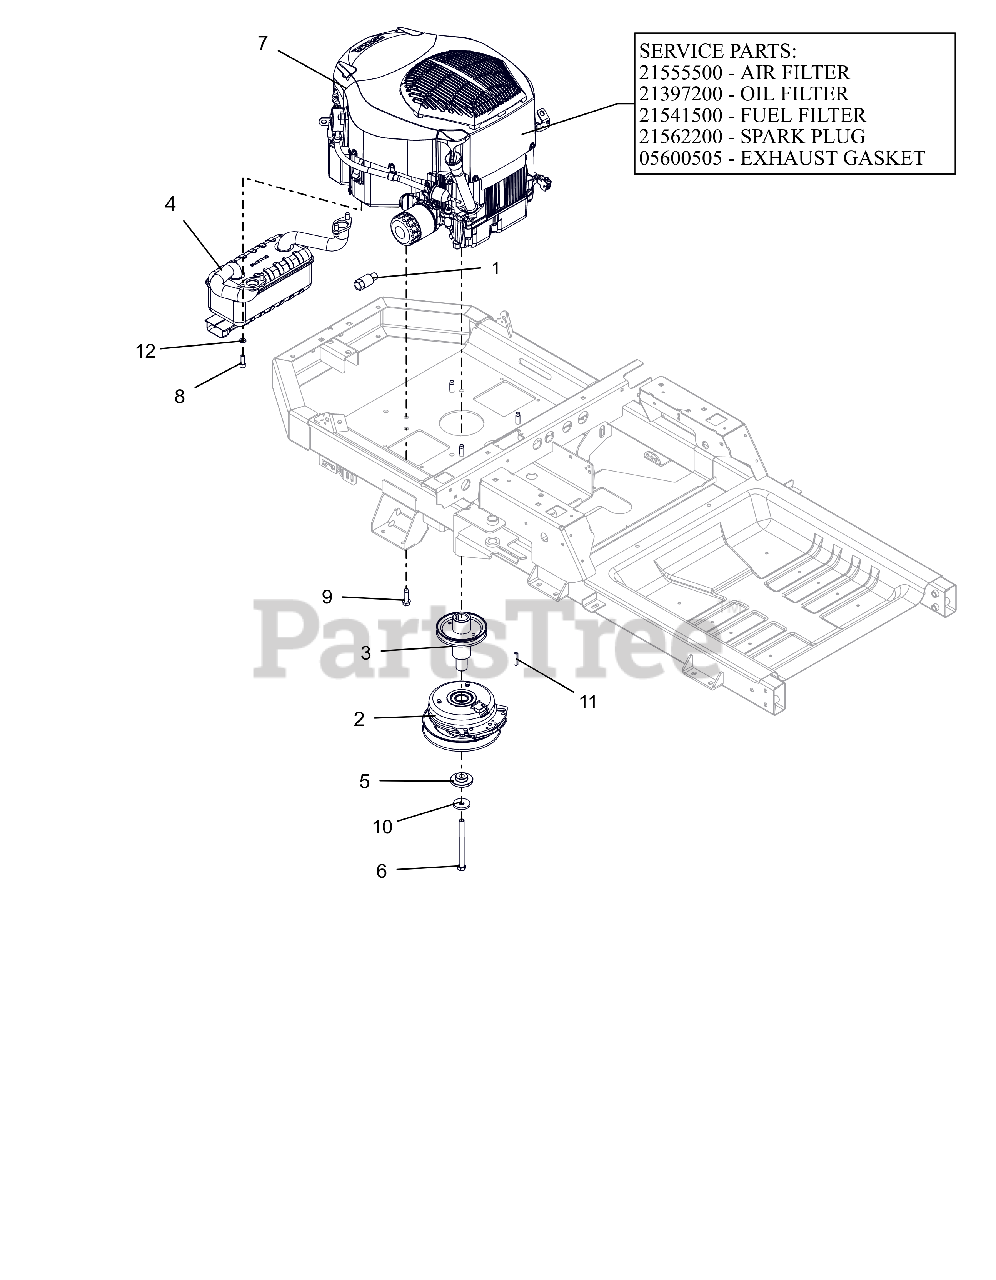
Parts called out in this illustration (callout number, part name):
1	DRAIN, OIL
2	CLUTCH,105FTLB MONOPOLE 6.83"
3	WLDMT, DRIVE SHEAVE (LG XL)CZC
4	MUFFLER, KOHLER
5	BSHG-FLG .469X1.06X.574X2.0
6	BLT-HEX.438-20X5 GR8 YZ NYTORQ
7	ENGINE, KOHLER 22HP TWIN
7	AIR CLEANER, KOHLER
7	FILTER, OIL - KOH CV20
7	FILTER, FUEL
7	PLUG, SPARK (RFI)
7	GASKET, MUFFLER COURAGE TWIN
8	SCR-CAP .31-18X.88 S/HD G8 ZCC
9	SCR,TAP .375-16X1.25HWH TR ZCC
10	WASHER, 7/16" SPRING DISK
11	KEY-SQ .25 X 1.25 X .25 SAE
12	WSHR,LK-REG .312X.078 ZCC
